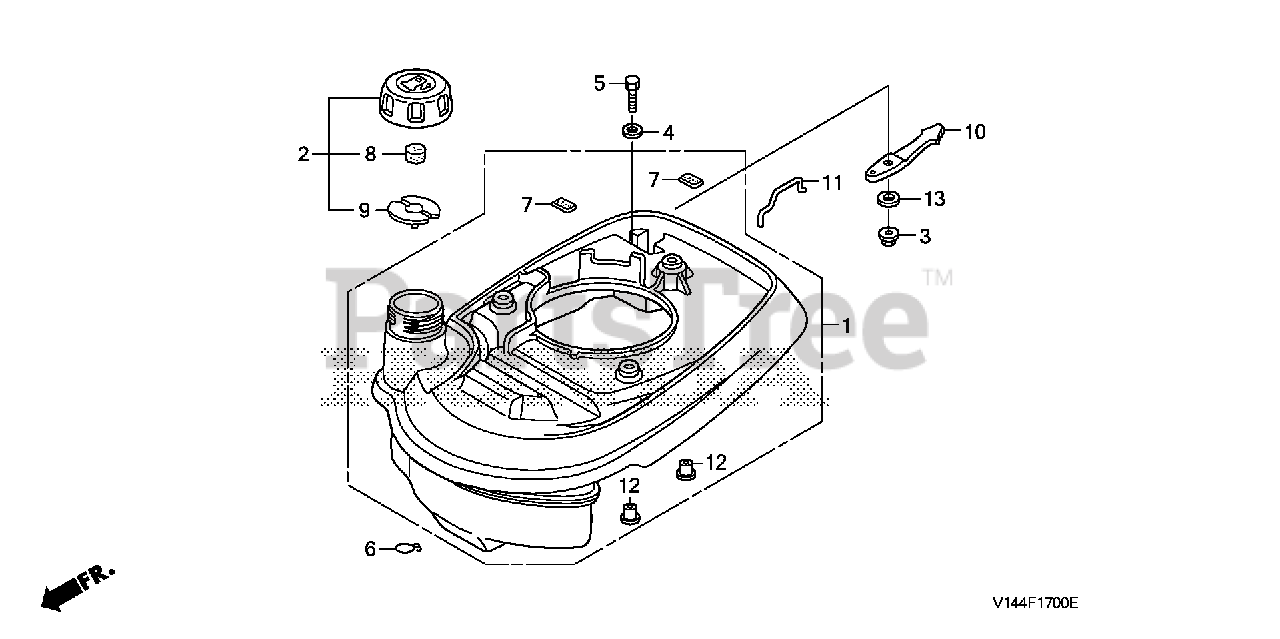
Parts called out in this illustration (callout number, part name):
1	TANK, FUEL *R280* (POWER RED)
2	CAP ASSY., FUEL TANK
3	NUT, SELF-LOCK (5MM)
4	WASHER (5MM)
5	BOLT, HEX. (5X22)
6	CLIP, TUBE (C9)
7	CUSHION, FUEL TANK
8	SPONGE, FUEL CAP BREATHER
9	GASKET, FUEL CAP
10	LEVER, CHOKE
11	ROD, CHOKE
12	COLLAR, FAN COVER
13	WASHER, PLAIN (8MM)
